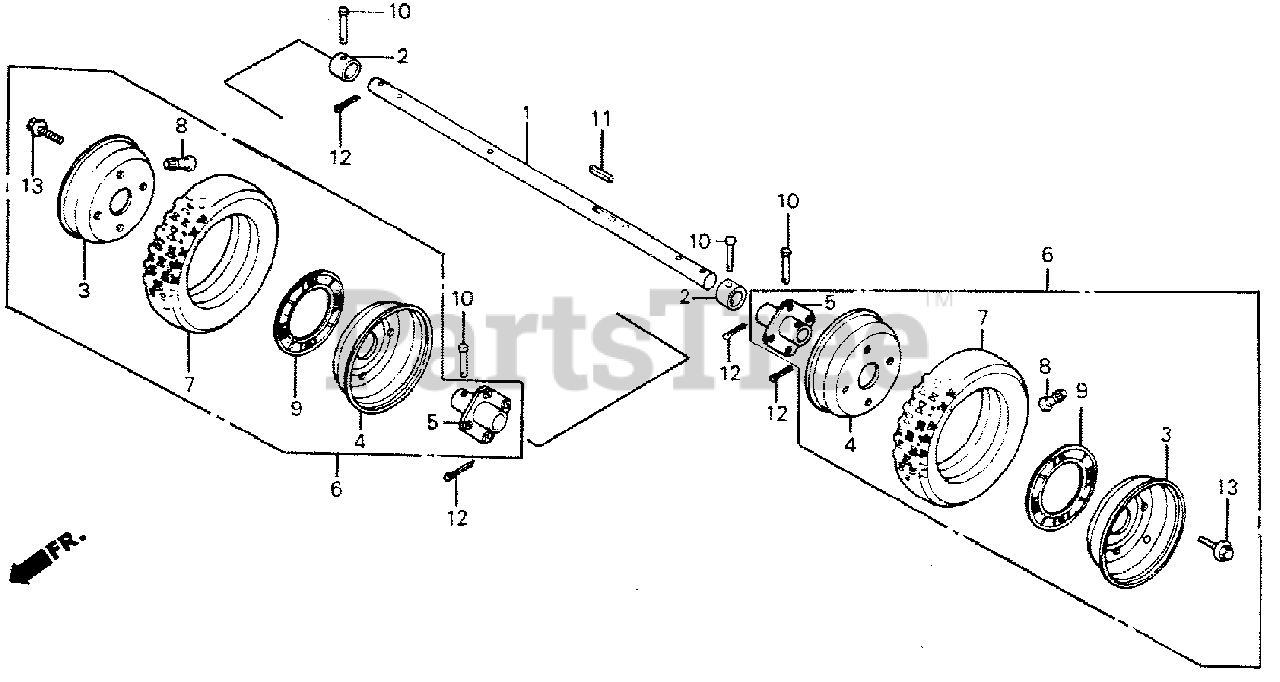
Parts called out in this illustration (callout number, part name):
1	SHAFT, WHEEL
2	COLLAR, WHEEL SHAFT
3	WHEEL A (3SPWX6DCT)
4	WHEEL B (3SPWX6DCT)
5	HUB, TIRE (HA-TYPE)
6	TIRE ASSY. (14X4.0-6) (B-905)
7	TIRE (14X4.0-6)
8	VALVE, RIM (SCHRADER)
8	VALVE, RIM (BS)
8	VALVE, RIM (TAIHEIYO)
9	GASKET (U-75)
10	PIN (6.2X38)
11	KEY (5X5X21)
12	PIN, COTTER (3.0X18)
13	BOLT, FLANGE (8X16)
